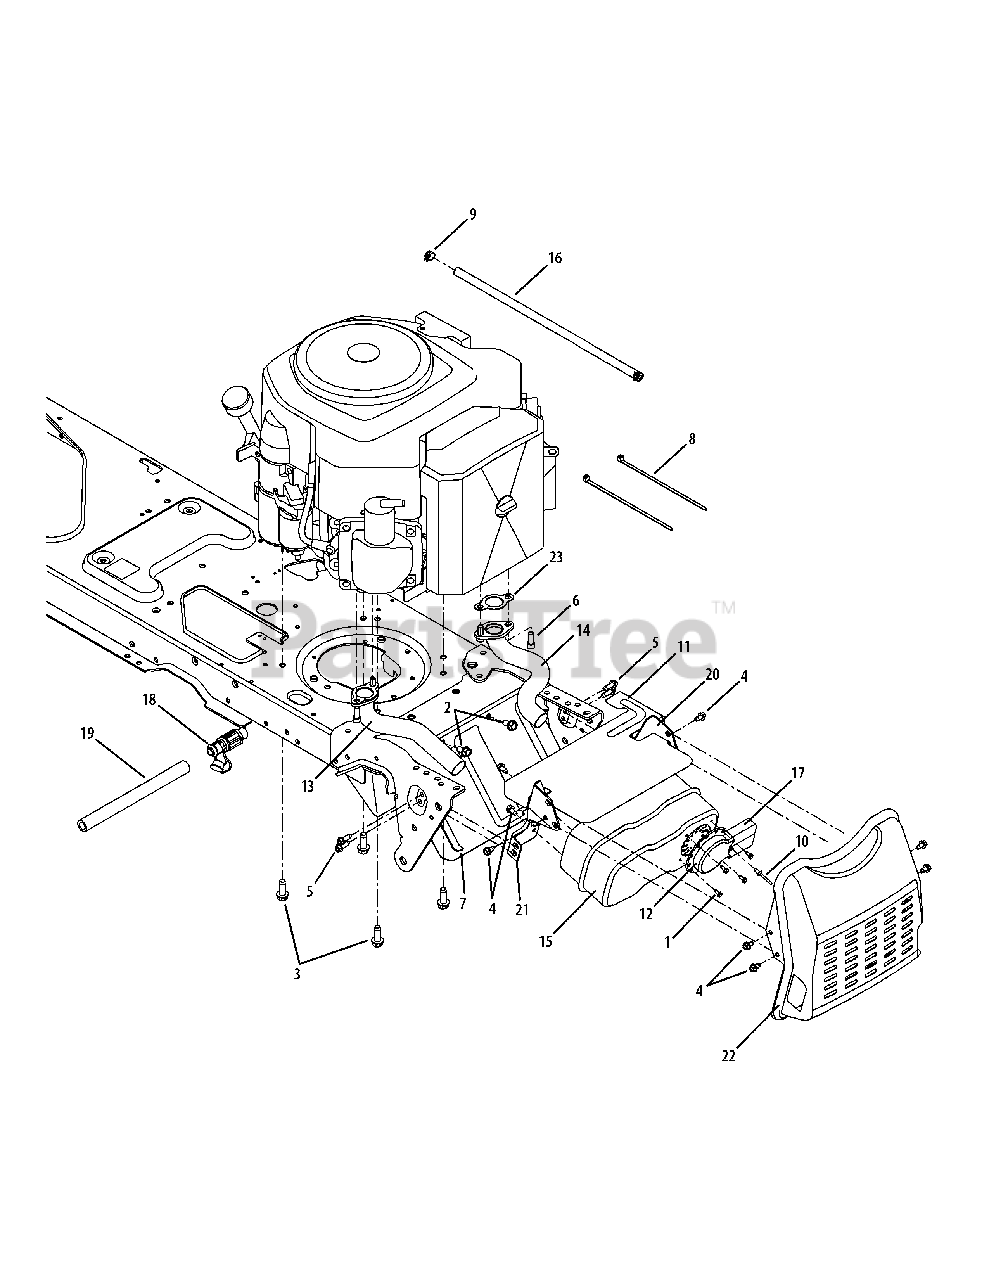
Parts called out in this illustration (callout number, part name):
1	Screw, #8-18, 0.500
2	Screw, 5/16-18, 0.750
3	Screw, Hex, 3/8-16 x 1.00
4	Screw, Hex, 1/4-20, 0.500
5	Screw, Hex, 1/4-20, 0.750
6	Screw, 5/16-18, 0.75
7	Muffler Heat Shield
8	Cable, Tie, 3/16 x .05 x 7.4
9	Hose Clamp
10	Rivet, Pop, .188 x .325
11	Heat Shield, Twin
12	Deflector, Muffler
13	Pipe, Exhaust, RH
14	Pipe, Exhaust, LH
15	Muffler, Dual Inlet
16	Fuel Line, Low Permeation
17	Extension, Deflector
18	Drain, Oil
19	Extension Hose, Oil Drain
23	Exhaust Gasket
